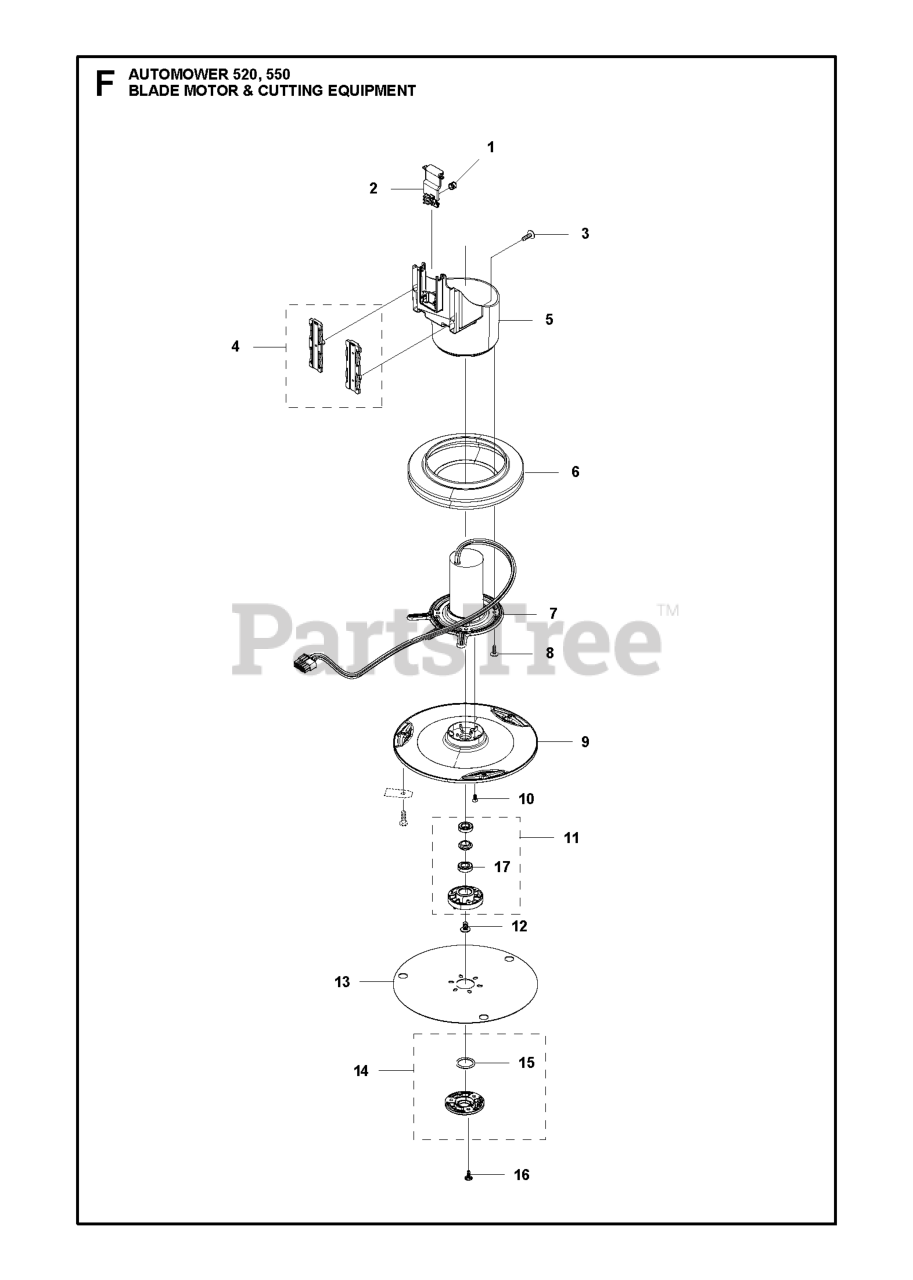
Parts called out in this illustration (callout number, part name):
1	SPRING LINK
2	LINK MOTOR HOUSING
3	SCREW 14MM
4	BEARING KIT
5	HOUSING CUTTING MOTOR
6	BELLOWS CUTTING SYSTEM
7	MOTOR ASSY JE
8	SCREW 14MM
9	CUTTING DISC
10	SCREW TORX M4X8 8.8 NYLON PATC
11	BEARING HOUSING ASSY
12	SCREW
13	SKID PLATE
14	COVER KIT BEARING
15	O-RING 20X2,5 MM
16	SCREW 14MM
17	BALL BEARING BALL BEARING 535
17	BEARING CUTTING DISC
17	BALL BEARING 2 RS,TIGHT CLEAR
